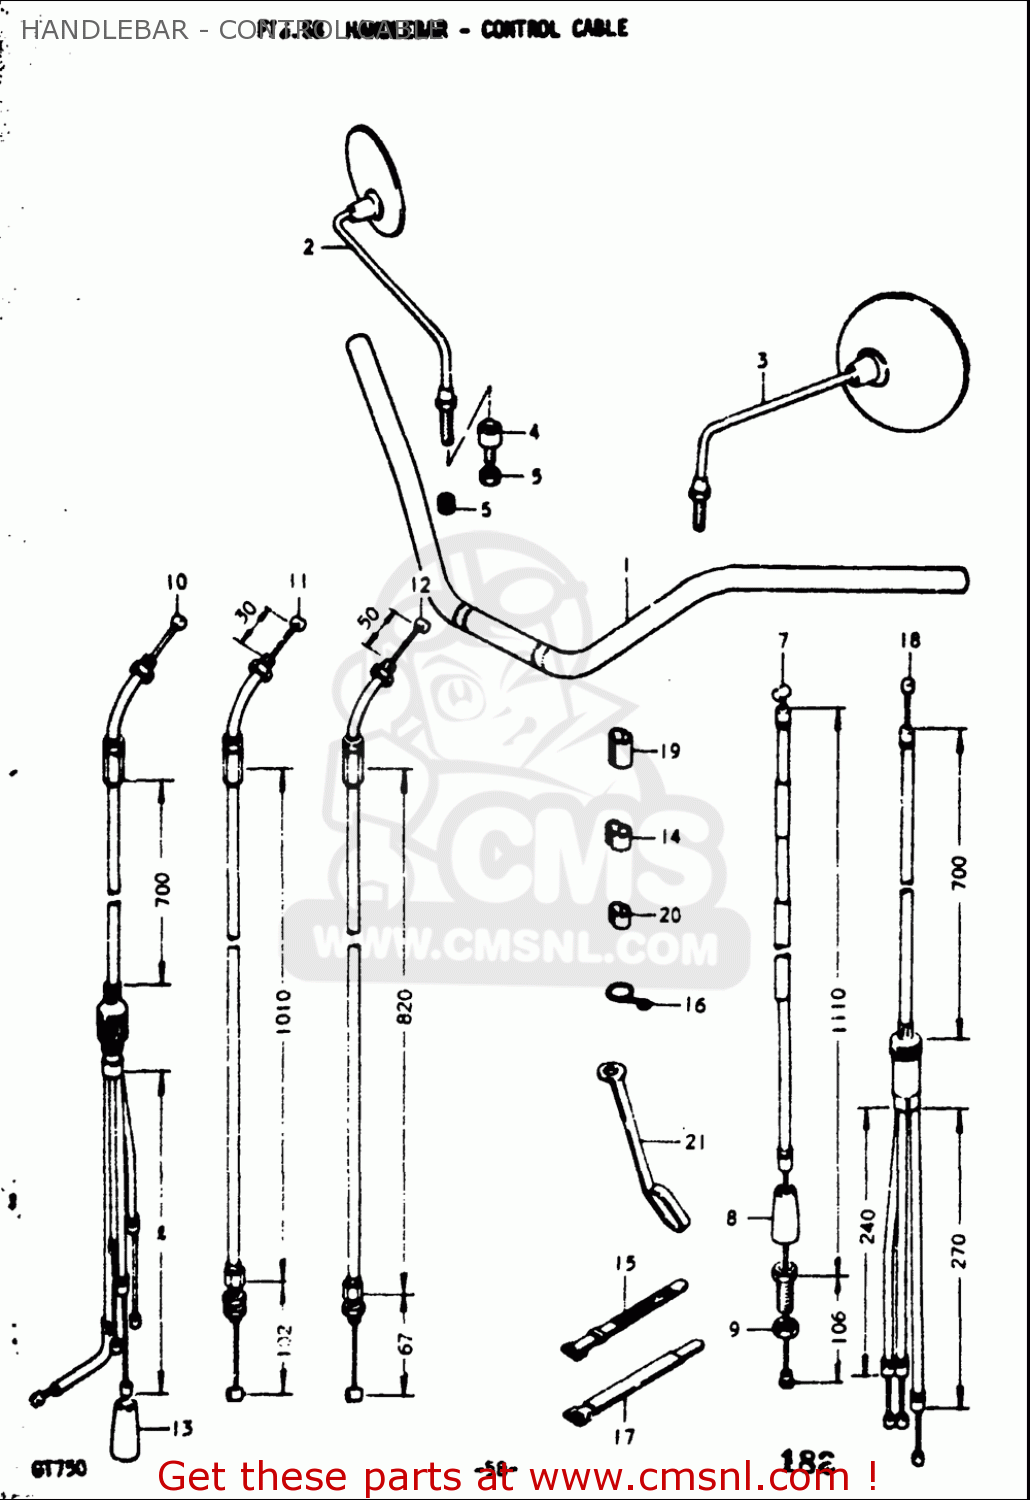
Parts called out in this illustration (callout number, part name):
1	HANDLEBAR
2	MIRROR ASSY,RE
3	MIRROR ASSY,LEFT
4	CUSHION ASSY,RR VIEW MIRROR
5	NUT
7	WIRE,CLUTCH
9	NUT
10	CABLE ASSY,THROTTLE
11	CABLE ASSY,THROTTLE NO.1
12	CABLE ASSY,THROTTLE NO.2
13	SEAL,DUST(7X18X30)
14	CLIP
15	CLAMP(L:120)
16	CLIP
17	CLAMP
19	CLIP
20	CLIP
